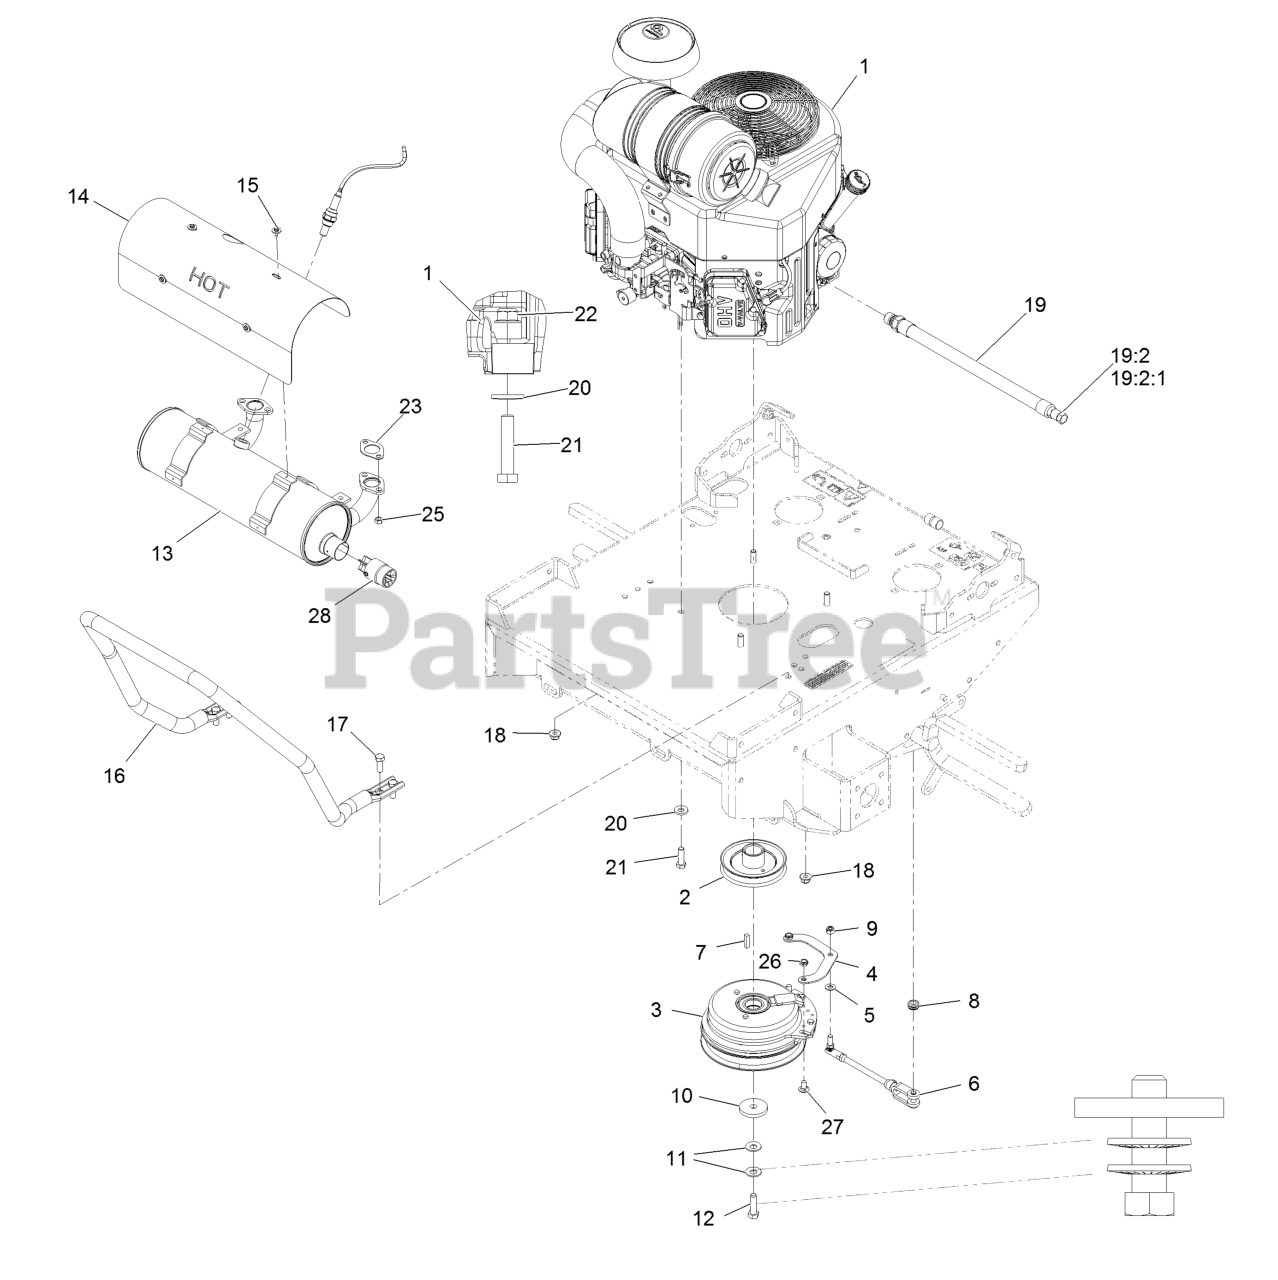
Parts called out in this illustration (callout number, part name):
2	Sheave W/ Hub
3	Clutch, 200 Ft/Lbs, 1.13
4	Strap, Clutch
5	Washer-5/16 SAE
6	ASM, Clutch Anchor
7	Key-Machine 1/4 X 1/4 X 1
8	Grommet
9	Nut-Lock 5/16-24
10	Washer-Clutch
11	Washer-Spring Disc 7/16
12	Bolt-Hex, TAP
13	Muffler-Ttx, Efi
14	Shield-Muffler,Ttx Efi
15	Screw-HH, Thread Forming
16	Guard,Air Cleaner
17	Screw-HH 3/8-16 X 1
18	Nut-Nyloc 3/8-16 Flg
19	Oil Drain Hose ASM
19:2	Plug-W/O-Ring
19:2:1	O-Ring
20	Washer-Spring Disc 5/16
21	Screw-HH 5/16-18 X 1 1/2
22	Nut-Nyloc 5/16-18 Flg
23	Gasket-Exhaust
25	Nut-Flange
26	Nut-Nyloc 5/16-18 Thin
27	Bolt-Carriage 5/16-18 X 5/8
28	Screen-Arrester, Spark
